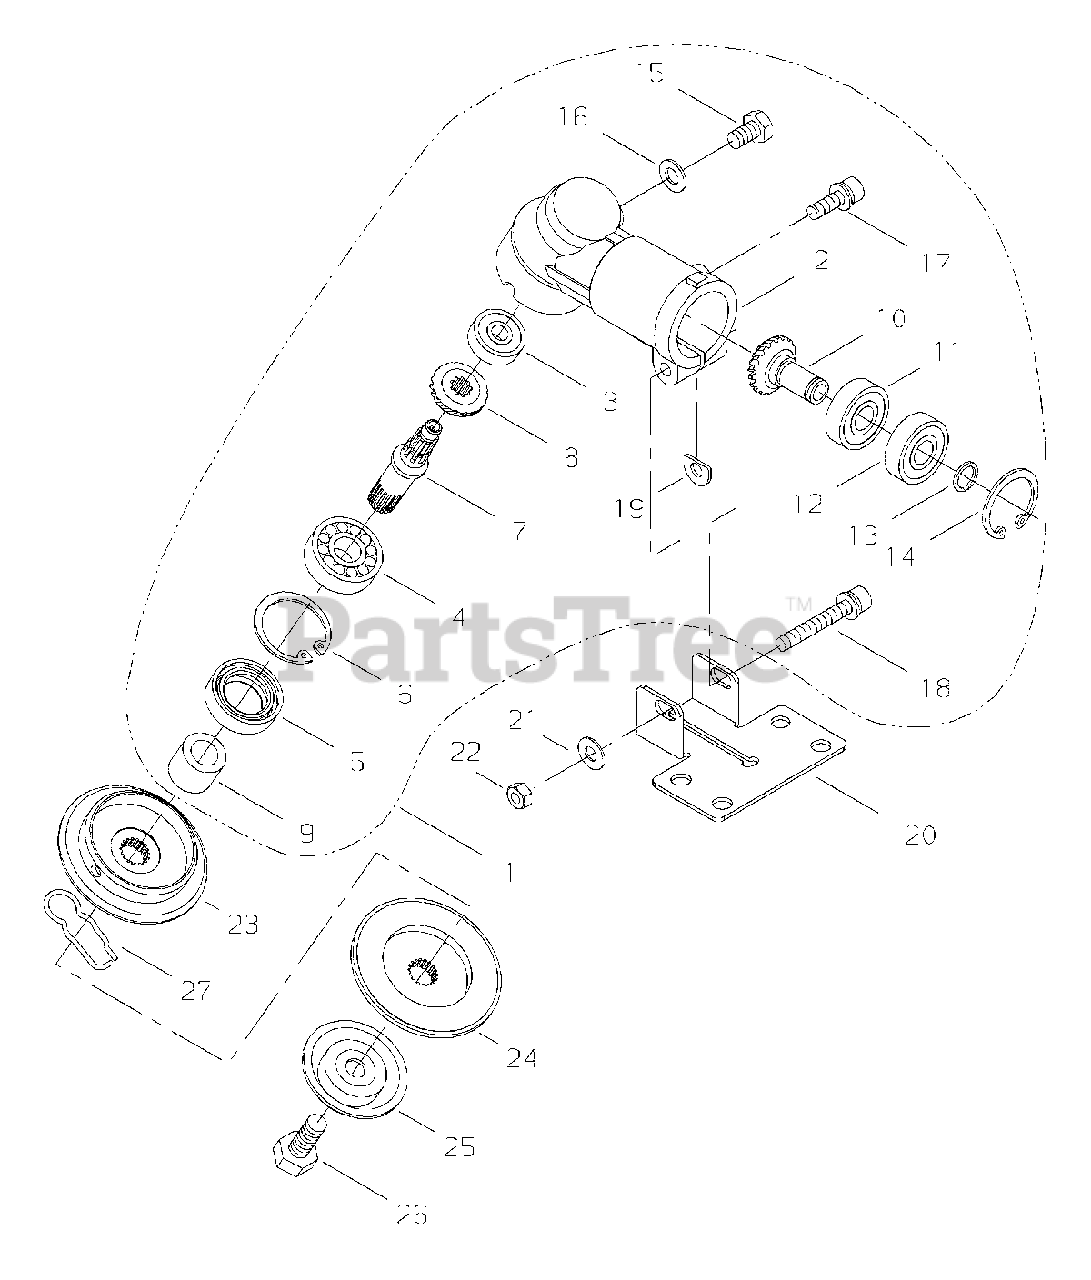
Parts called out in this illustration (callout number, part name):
1	GEAR CASE ASSY
2	CASE, GEAR
3	BEARING, BALL - 609
4	BEARING, BALL - 6201
5	SEAL, OIL
6	RING, RETAINING - 32
7	GEAR - SHAFT
8	GEAR - BEVEL
9	COLLAR
10	PINION SET
11	BEARING, BALL - 6901
12	BEARING, BALL - 6901ZZ
13	RING, RETAINING
14	RING, RETAINING - 24
15	BOLT - 6X10
16	WASHER
17	SCREW - 5X16
18	SCREW - 6X40
19	SHIM
20	BRACKET
21	WASHER - 6
22	NUT - 6
23	HOLDER - A
24	HOLDER
25	GUARD
26	BOLT - 8 -- LEFT HAND
27	CLIP
